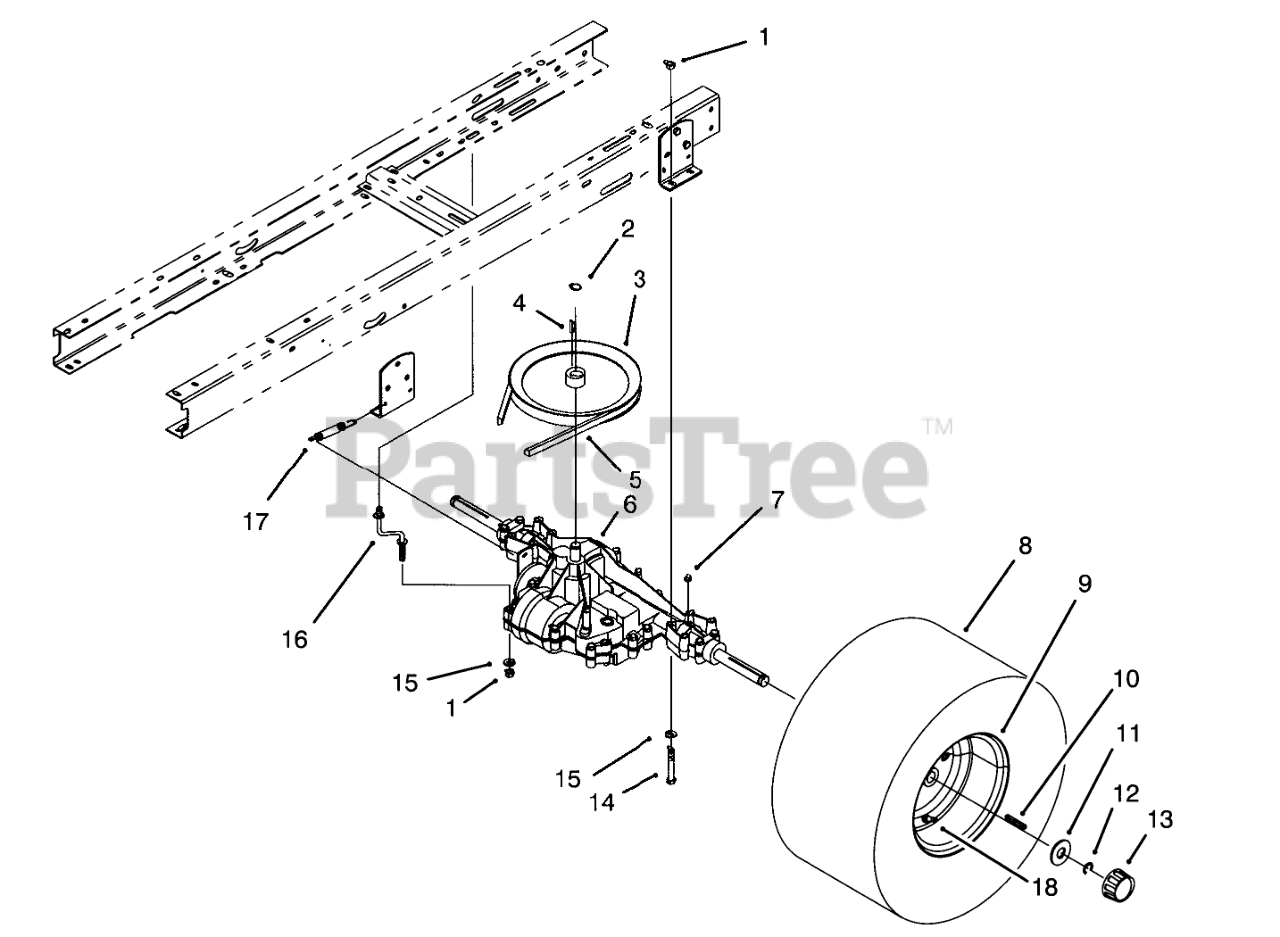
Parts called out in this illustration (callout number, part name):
1	NUT-LOCK, NI
2	RING-SNAP, EXTERNAL
3	PULLEY-TRANSMISSION
4	KEY-WOODRUFF
5	V-BELT
6	Transaxle
7	FITTING-LUBE, 45 DEG
8	TIRE 16 X 6.50 X 8
9	RIM ASM
10	KEY-SQUARE
11	WASHER-PLAIN
12	E-RING
13	CAP-HUB
14	SCREW-HH
15	WASHER-PLAIN
16	TORQUE STRAP
17	SPRING-RETURN, BRAKE
18	STEM-VALVE
